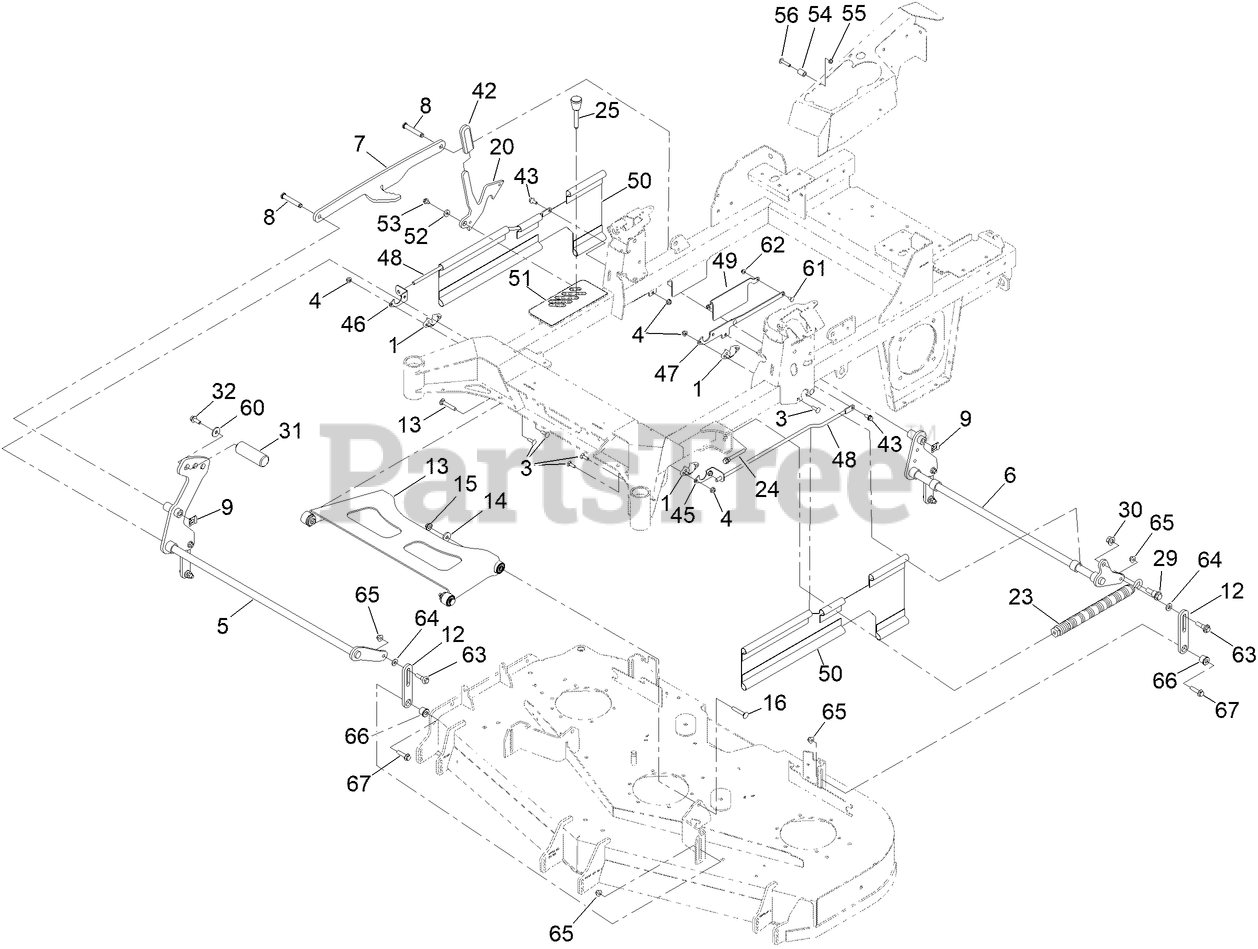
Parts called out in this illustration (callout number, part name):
1	BEARING-FLANGE
3	SCREW-CARR
4	NUT-HF, NI
5	SHAFT-LIFT, DECK
6	DECK LIFT SHAFT ASM [BLACK]
7	LINK-LIFT
8	PIN-CLEVIS
9	CLIP-PIN
12	LINK-LIFT, DECK
13	ASM-DECK STRUT W/ BUSHINGS
14	WASHER
15	NUT-FLANGE, NI
16	SCREW-CARR
20	PLATE-TRANSPORT LOCK
23	SPRING-EXTENSION
24	BOLT-SHOULDER
25	PIN-HOC
29	SCREW-SHOULDER, HHF
30	NUT-LOCK
31	PEDAL-FOOT LIFT
32	SCREW-HHF
42	GRIP-LEVER
43	SCREW-HHF
45	BRACKET-MOUNT, UPPER FRONT (LH)
46	BRACKET-MOUNT, UPPER FRONT (RH)
47	BRACKET-MOUNTING, UPPER
48	ROD-SUPPORT, UPPER
49	BRACKET-FLAG
50	GUARD-SIDE
51	DECAL-HOC, MM
52	SPACER
53	SCREW
54	SPACER
55	NUT-LOCK, NI
56	SCREW-TORX
60	WASHER
61	SCREW-CARR
62	NUT-HF
63	BOLT-SHOULDER
64	SPACER
65	NUT-HF, NI
66	BUSHING-DECK LIFT
67	SCREW-HHF
